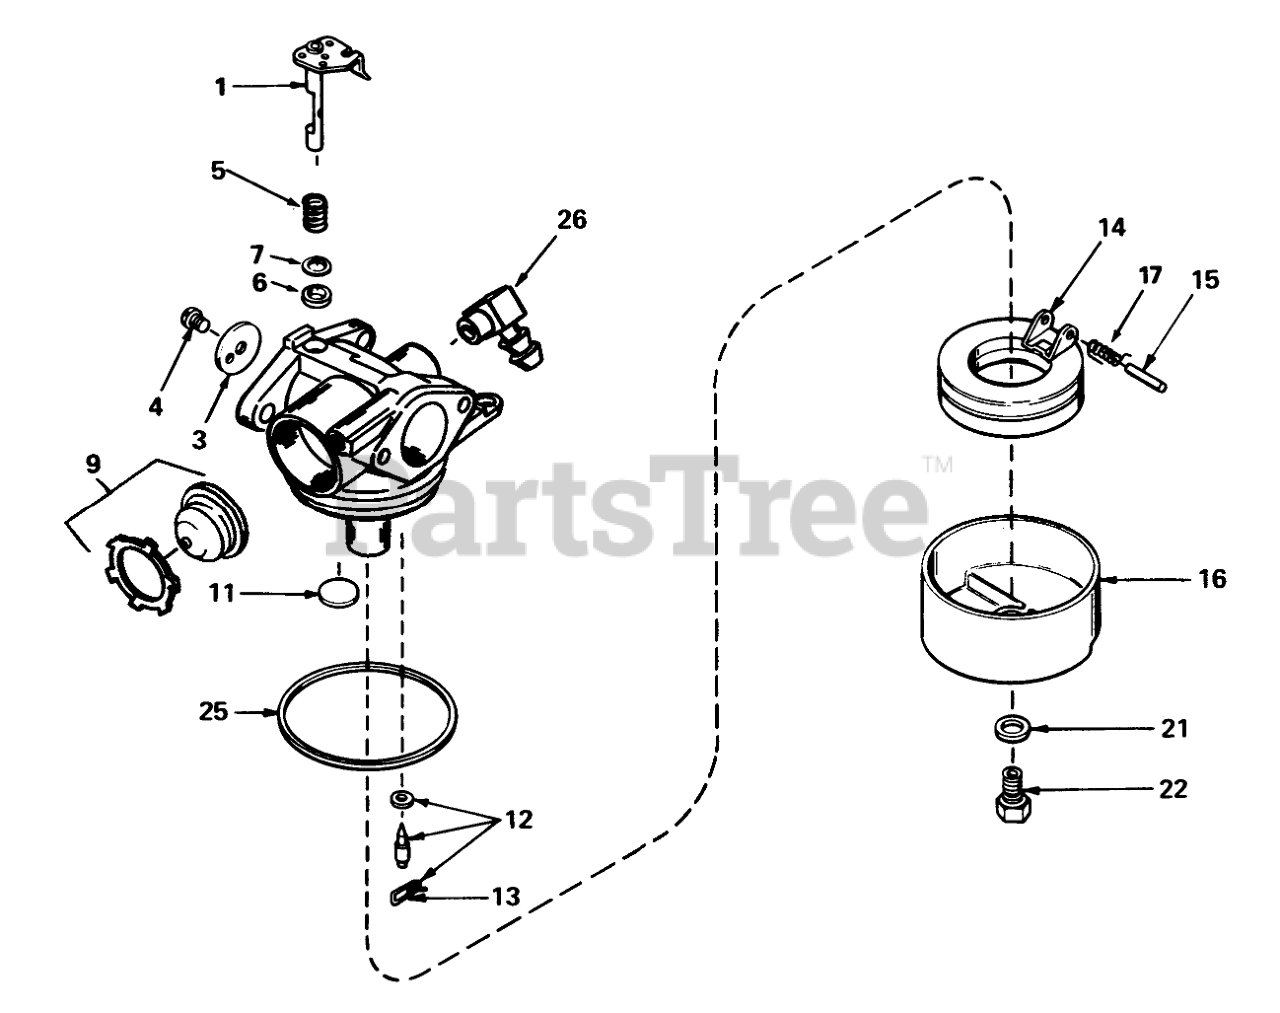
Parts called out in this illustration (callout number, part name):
1	Throttle Shaft and Lever ASM
3	Shutter-Throttle
4	Screw-Shutter
5	Spring-Return, Throttle
6	Seal-Dust
7	Washer-Seal, Dust
9	Bulb-Primer
11	Plug-Welch, Atmospheric Vent
12	Needle Seat & Clip Assy. (Incl. Ref. #13)
13	Clip-Spring
14	Float
15	Shaft-Float
16	Bowl-Float (no drain)
17	Spring-Float, Dampening
21	Washer-Bowl Nut
22	Nut-Float Bowl
25	O Ring-Bowl, Float
26	Fitting-Fuel
